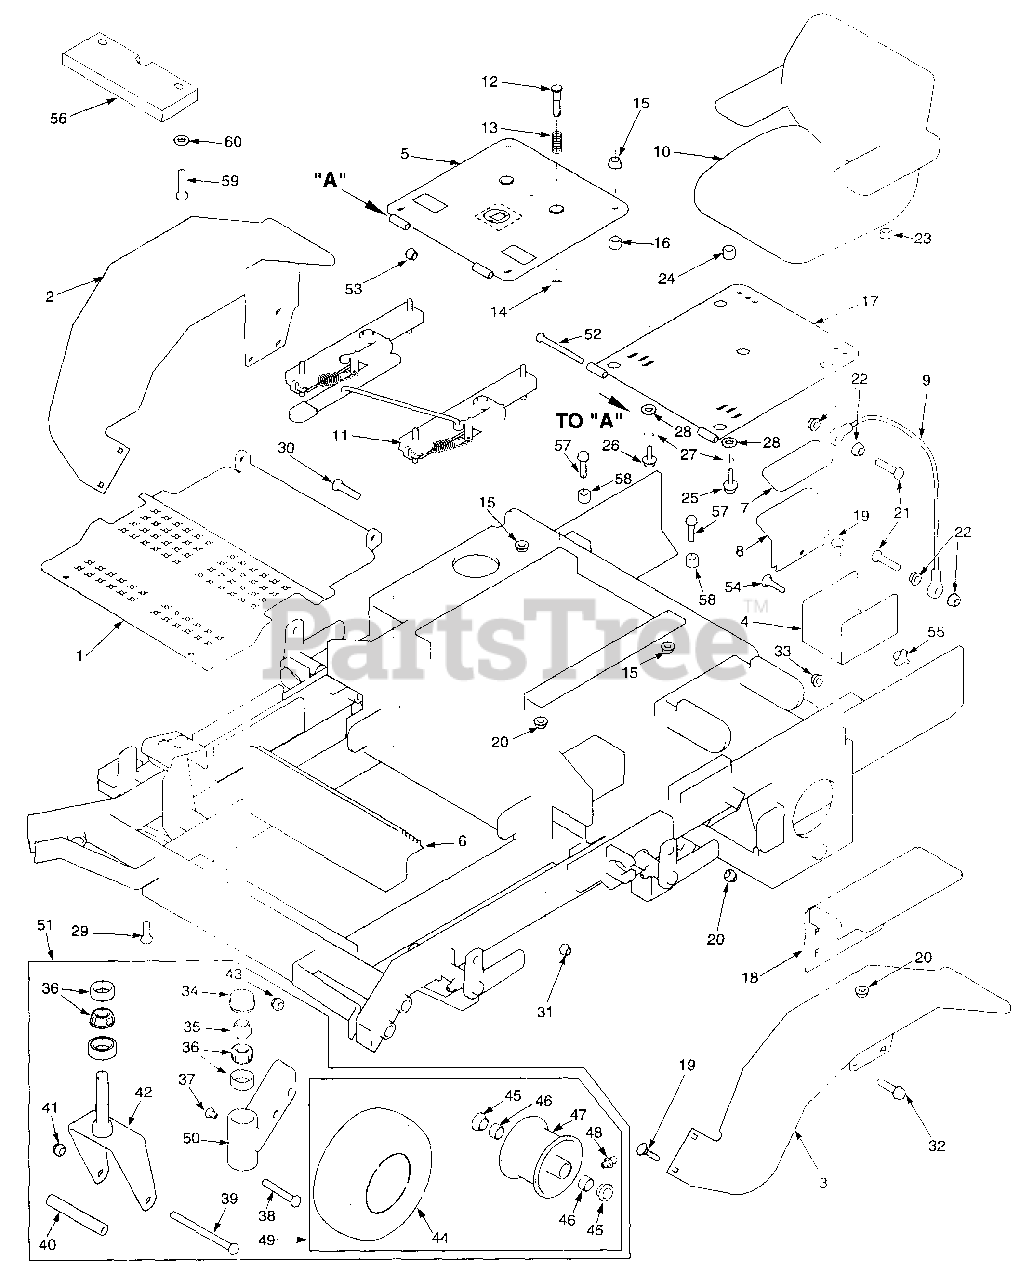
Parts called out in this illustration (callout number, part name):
1	Footplate
2	Fender, RH
3	Fender, LH
4	Box, Battery
5	Plate, Lower Seat
6	Footrest
7	Insulation, Battery Cover
8	Cover, Battery
9	Cable, Seat Stop
11	Track Set, Seat Adjuster
12	Pin, Spring
13	Spring, Seat
14	Spring Pin, .156 x .75"
15	Nut, Serr. Flg. 5/16-18
16	Spacer
17	Plate, Upper Seat
18	Bracket, Battery
19	Bolt, Carr. 5/16-18 x 3/4"
20	Nut, Serr. Flng. 5/16-18
21	Bolt, Hex Head 1/4-20 x 1-1/4"
22	Nut, 1/4-20
23	Spacer
24	Spacer
25	Bolt, Hex Head 5/16-18 x 1.5"
26	Bolt, Hex Head 5/16-18 x 2.25"
27	Lock Washer 5/16"
28	Flat Washer 5/16 .375 x .875 x .083
29	Bolt, Hex Head 1/2-13 x 1.5"
30	Bolt, Hex Head 3/8-16 x 1.0"
31	Nut, Elastic Stop 3/8-16
32	Capscrew, Serr. Flng. 3/8-16 x 1.00"
33	Nut, Serr. Flng. 3/8-16
34	Cap, Grease
35	Nut, Hex Elastic Stop 1.0-14
36	Bearing w/ Race
37	Plug, 1/4-28 THD Form
38	Bolt, Hex Head 5/8-11 x 4.00"
39	Bolt, Hex Head 1/2-13 x 7.5"
40	Spacer
41	Nut, Hex Head Elastic Stop 1/2-13
42	Yoke Weldment, Caster
43	Nut, Elastic Stop 5/8-11
45	Bearing, Oilite
46	Bearing, Roller
47	Rim Assembly
48	Fitting, Grease
49	Wheel Assembly
50	Extension, Caster Wheel LH, 61"
51	Caster Wheel Assembly LH, 61"
52	Bolt, Hex Head 5/16-18 x 3.50"
53	Nut, Hex Head Elastic Stop 5/16-18
54	Bolt, Carriage 1/4-20 x 6.00"
55	Wing Nut 1/4-20 x .75"
56	Weight
57	Bolt, Hex Head 5/16-18 x 1.75"
58	Spacer
59	Bolt, Hex Head 1/2-13 x 3.5"
60	Flat Washer 1/2-.562 x 1.375 x .109
